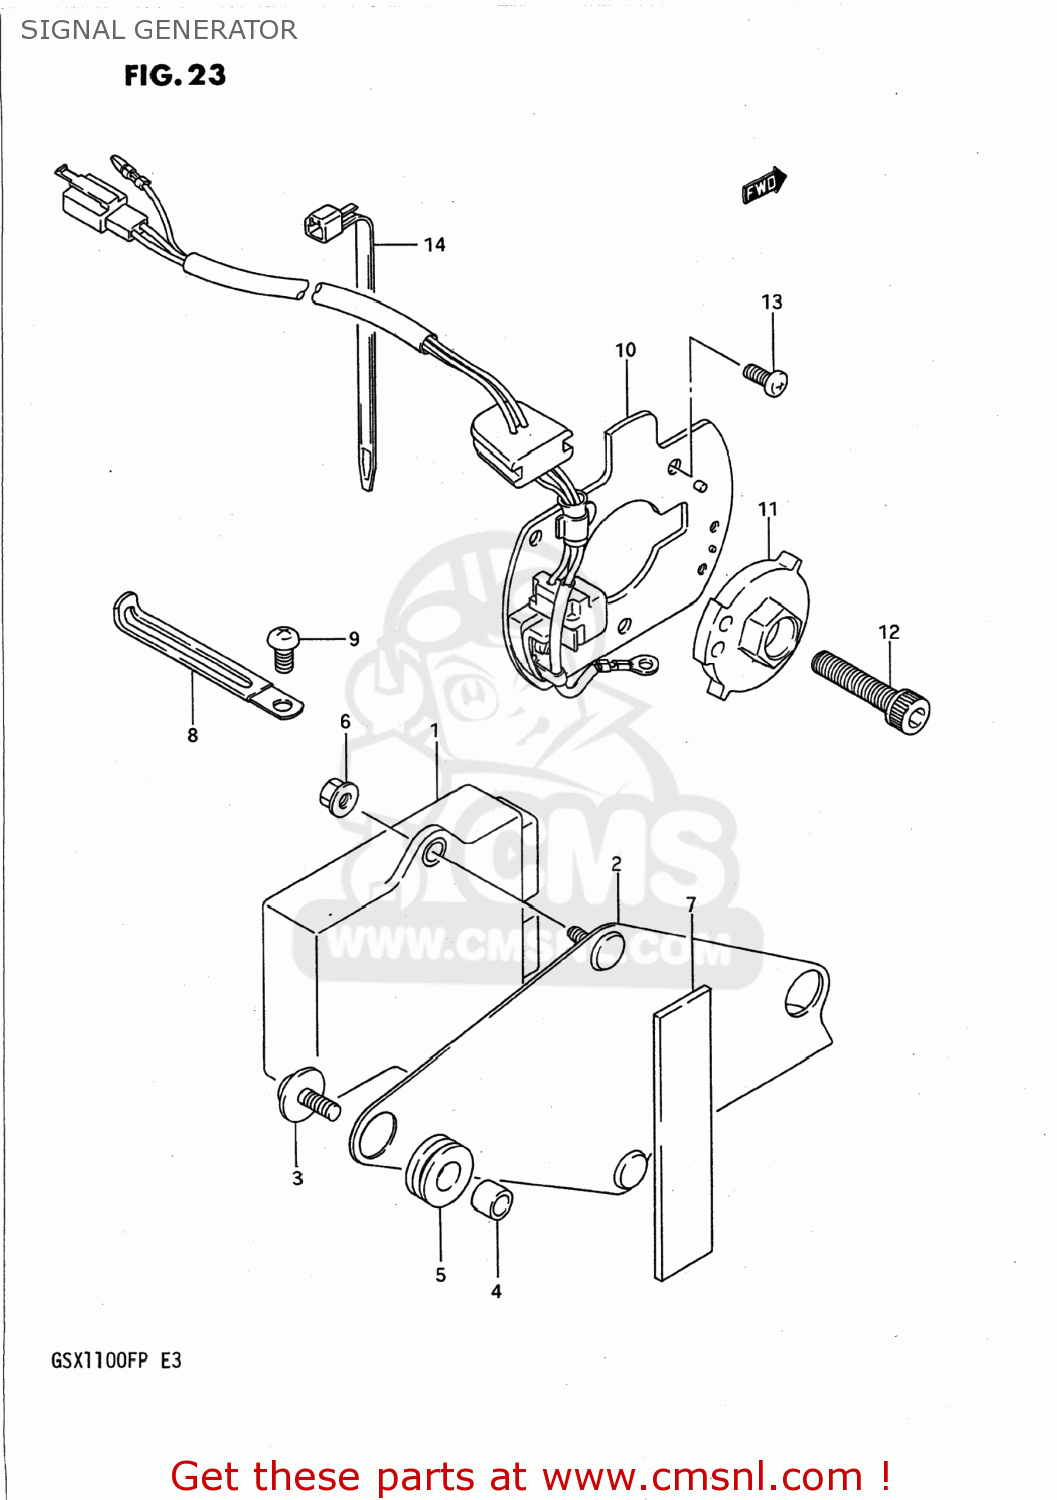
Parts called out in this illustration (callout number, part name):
1	IGNITOR UNIT ASSY
2	PLATE COMP,IGNITER
3	SCREW(6X16)
4	SPACER(6.1X9X7.5)
5	CUSHION
6	NUT
7	PROTECTOR,20X9
8	CLAMP
9	SCREW
10	GENERATOR ASSEMBLY,SIGNAL
11	ROTOR,SIGNAL
12	BOLT
13	SCREW
14	CLAMP(L:125)
